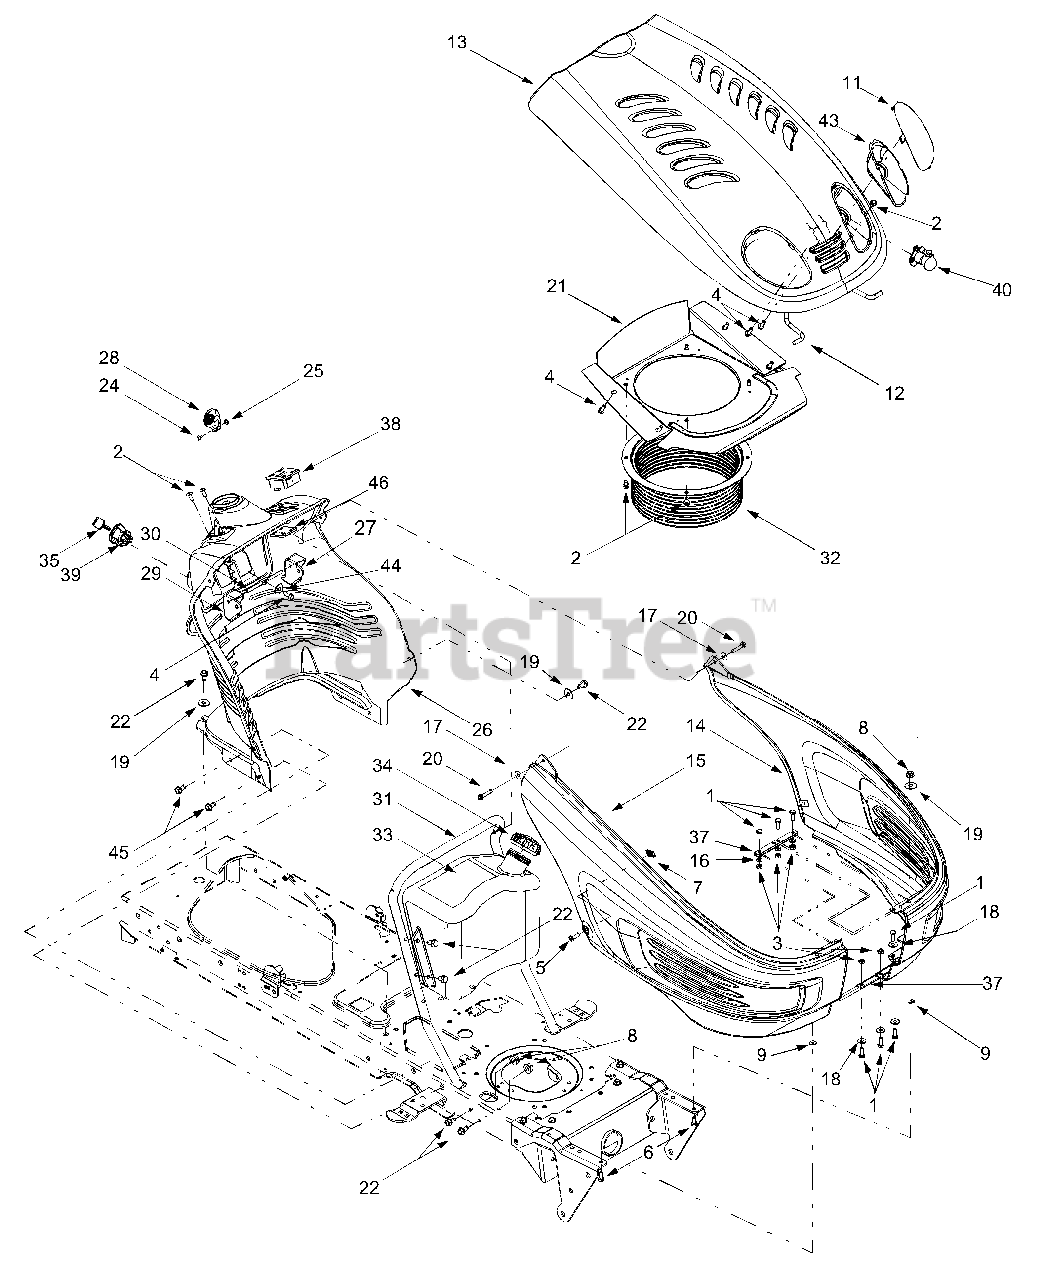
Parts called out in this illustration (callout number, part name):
1	Hex Cap Screw, 1/4-20 x.75
2	Self-tapping Screw, 1/4-20 x.5
3	Hex Nut, 1/4-20
4	Self-tapping Screw, 1/4-15 x.75
5	Pan Phillips Screw, 1/4-20 x.75
6	Hex Cap Screw, 5/16-18 x 1.25
7	U-type Speed Nut, 1/4-20
8	Flange Lock Nut, 5/16-18
9	Speed Nut
11	RH Head Light Lens
12	Hood Support Rod
13	Hood
14	LH Side Panel
15	RH Side Panel
17	Flat Washer,.283 x.75 x.030
18	Flat Washer,.28 x.74 x.063
19	Flat Washer,.349 x 1.0 x.063
20	Self-tapping Screw, 1/4-20 x.750
22	Self-tapping Screw, 5/16-12
24	Torx Screw, #8-32 x.375
25	Hex Nut, 8-32
26	Dash Panel, 4-style
27	Parking Brake Lever
28	Throttle Control Lever
29	Cruise Control Lever
30	Brake/Cruise Pivot Rod
33	Fuel Tank, 3-gallon
34	Fuel Cap
35	Ignition Key w/ plastic cover
39	Ignition Switch
40	Lamp Socket
43	RH Headlight Reflector
44	Flat Washer,.281 x.50 x.063
45	Self-Tapping Screw, 5/16-18
46	Electric PTO Switch Bracket Retainer
